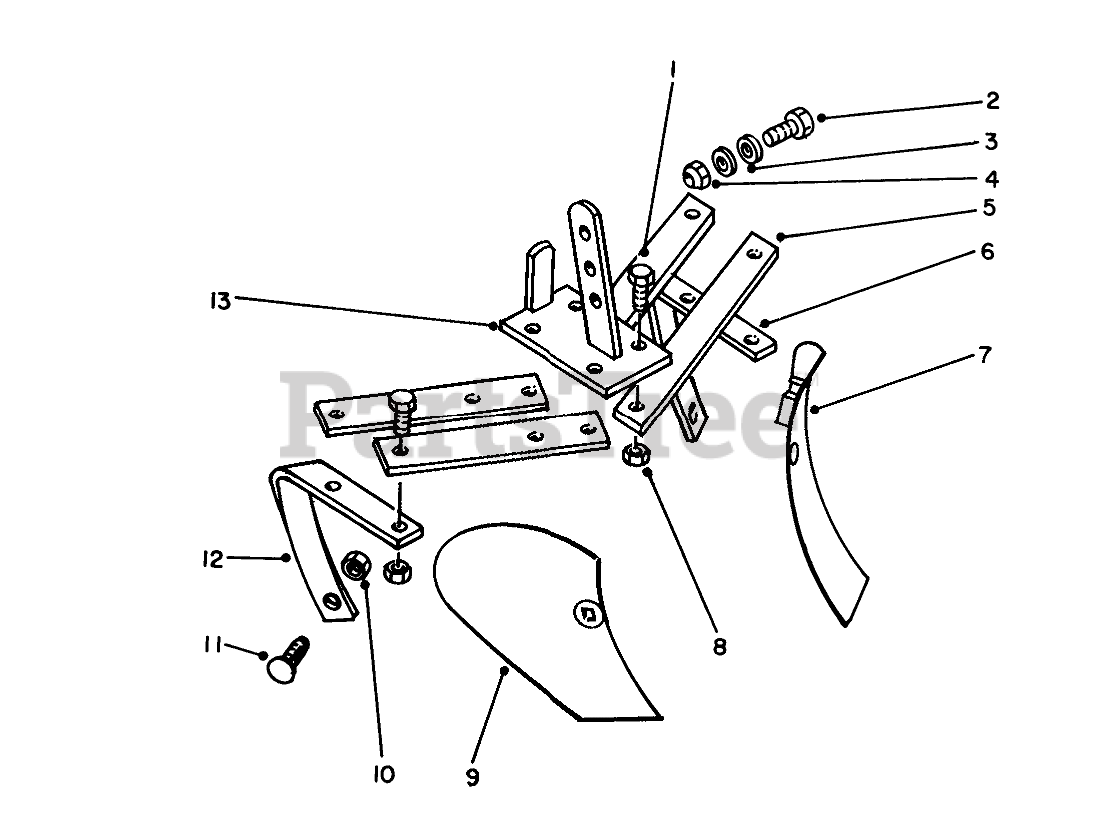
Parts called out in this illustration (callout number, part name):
1	SCREW-HH
2	SCREW-HH
3	WASHER-FLAT
4	Locknut-Hex Cone
5	Attachment Bar
6	Blade Holder-L.H. Turning
7	Plow-L.H.
8	NUT-LOCK, CONE
9	Turning Plow-R.H.
10	NUT-LOCK, CONE
11	Plow Bolt
12	Blade Holder-R.H.
13	Hitch
